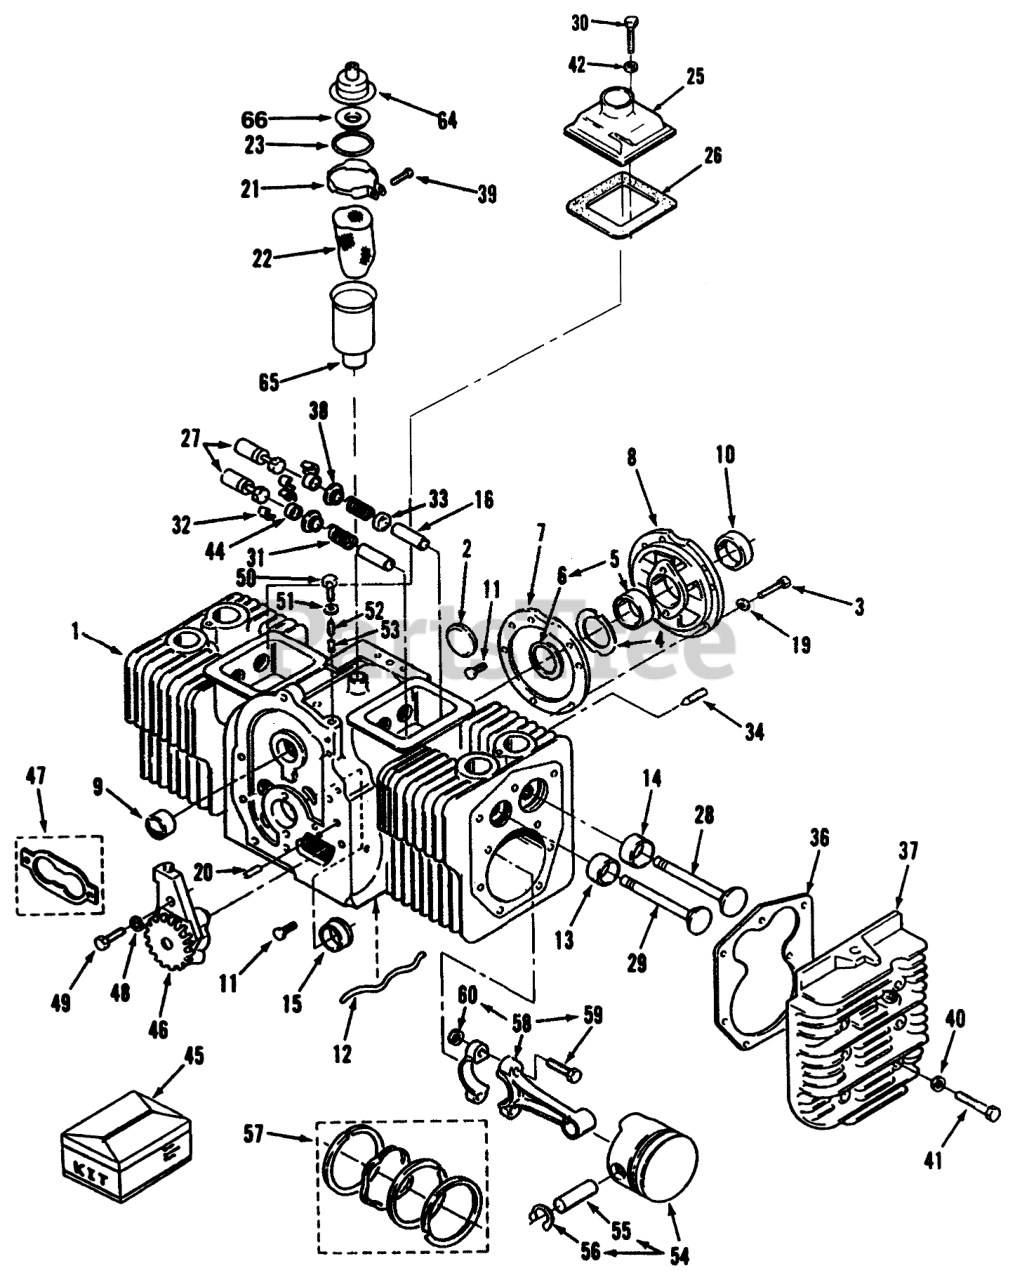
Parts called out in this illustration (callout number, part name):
1	CYLINDER BLOCK
3	HEX HD CAPSCREW
5	BEARING KIT (STANDARD SLEEVE)
6	WASHER
7	GASKET
8	PLATE-BEARING, REAR
9	SLEEVE-BEARING
11	PIN-DRIVE
12	Tube-Oil
13	STD INSERT
14	STD INSERT
15	KIT-BEARING, SLEEVE
16	EXHAUST VALVE GUIDE
19	WASHER-LOCK
20	PIN-GEAR COVER
21	Clamp
22	FILTER
23	SEAL - O-RING
25	Cover-Valve
26	GASKET
27	TAPPET
28	INTAKE VALVE
29	EXHAUST VALVE
30	HHCS 1/4-20 X 1 3/4
31	Spring
32	VALVE SPRING LOCK
33	VALVE STEM SEAL
34	SCREW-SET
36	GASKET
37	CYL RS HEAD
38	Washer
40	WASHER
41	Screw-HH
42	WASHER
44	VALVE CAP
45	ENGINE GASKET KIT
47	GASKET KIT
48	WASHER-FLAT
49	SCREW - CAP HEX HEAD
50	SCREW-HH
51	WASHER
52	SPRING
53	PLUNGER
54	STD PISTON KIT
55	PISTON PIN
56	Piston Pin
57	RING/PISTON KIT
58	Rod w/Bolts & Nuts-STD
58	CONNECTING ROD W/NUT
64	BREATHER-CAP AND VALVE
65	TUBE-BREATHER
66	SCREEN-BREATHER TUBE
